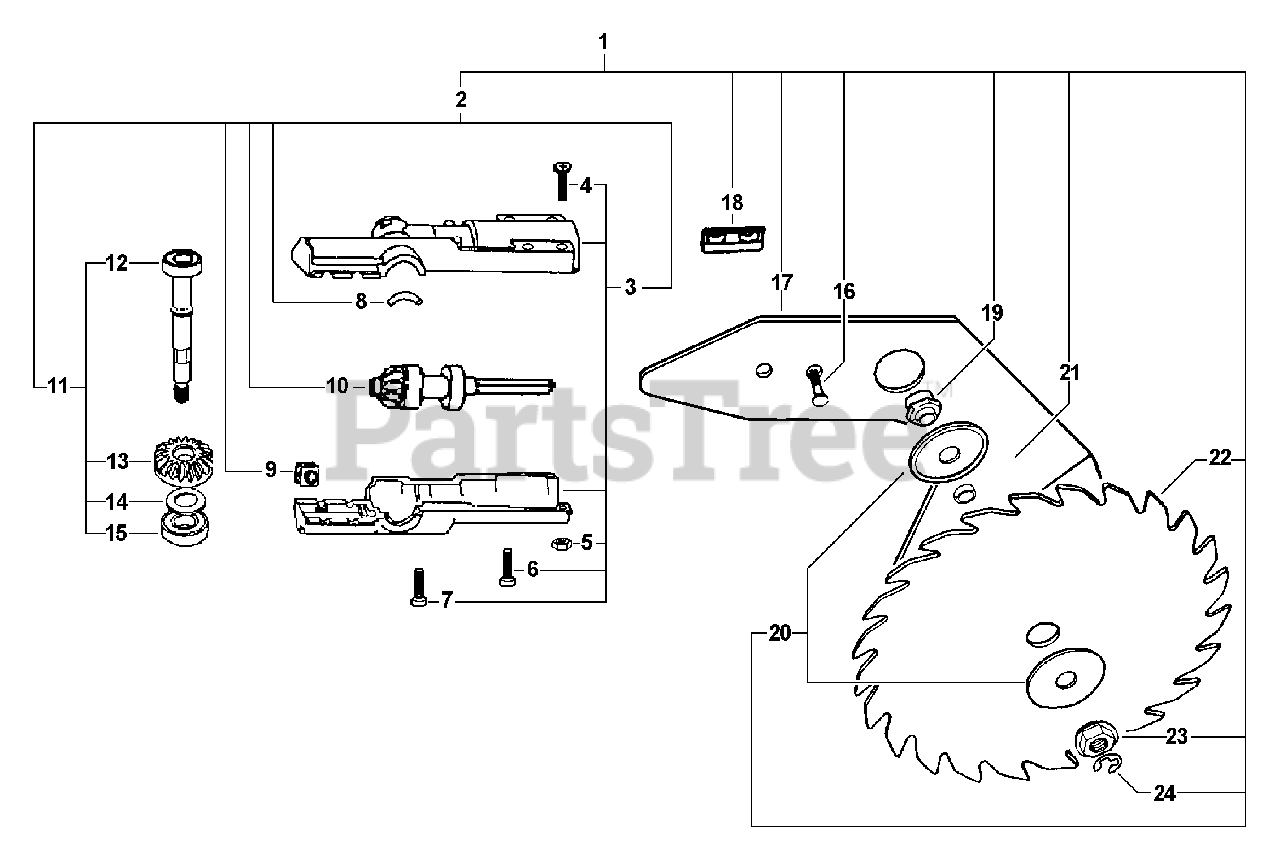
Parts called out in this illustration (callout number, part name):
1	CIRCLE SAW ACCESSORY
2	GEAR CASE ASSY
3	GEAR CASE ASSY
4	SCREW - 10-24 X 1-1/4"
5	LOCKNUT - 10-24
6	SCREW
7	SCREW - 10-24 X 7/8"
9	SPACER
10	SHAFT GEAR ASSY
11	SHAFT GEAR ASSY
12	SHAFT GEAR ASSY
13	GEAR - BEVEL
15	BEARING, BALL - 6001
17	SHIELD, BLADE
18	BRACKET, GUIDE BAR
19	MOUNT, BLADE
20	SAW COLLAR
21	ADAPTOR
22	BLADE
23	NUT - FLANGE
24	RING, RETAINING
